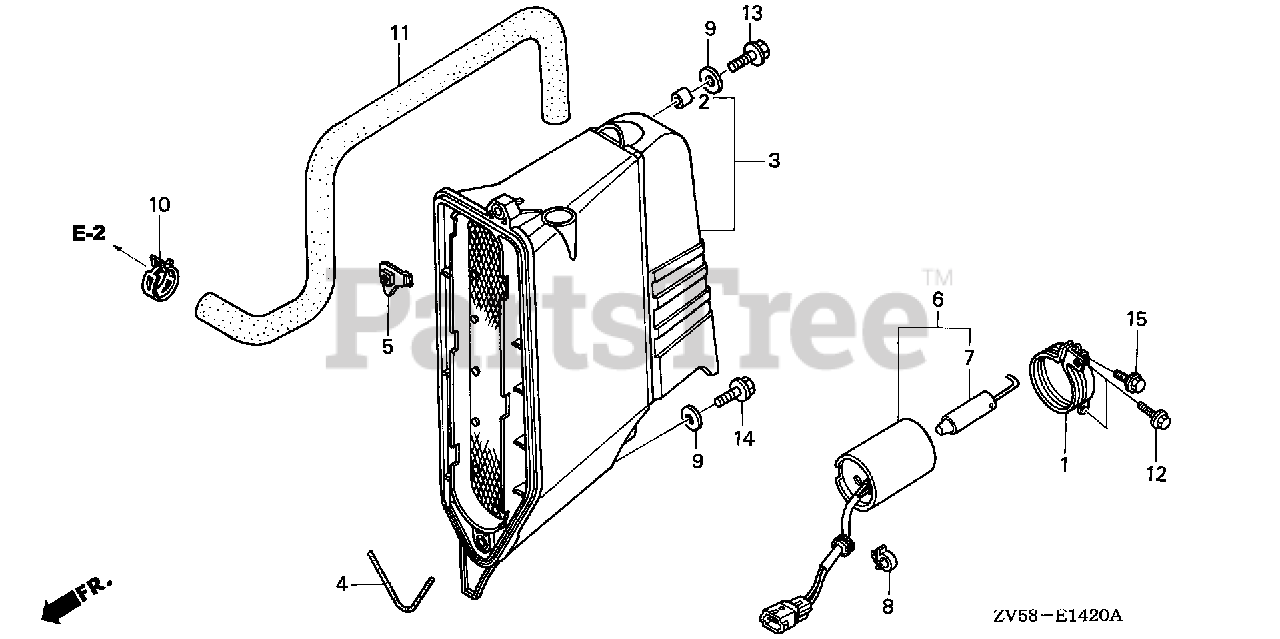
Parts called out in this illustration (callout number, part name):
1	STAY, SOLENOID
2	COLLAR, DISTANCE
3	COVER, MUFFLER
4	GASKET, MUFFLER COVER
5	NUT, MUFFLER COVER
6	SOLENOID ASSY., REMOTE CHOKE
7	PLUNGER, SOLENOID
8	HOLDER, ROD (6MM)
9	WASHER (6.5X18)
10	CLAMP, TUBE (D17)
11	TUBE, BREATHER
12	BOLT, FLANGE (6X14)
13	BOLT, FLANGE (6X25)
14	BOLT, FLANGE (6X40)
15	BOLT, FLANGE (6X12)
